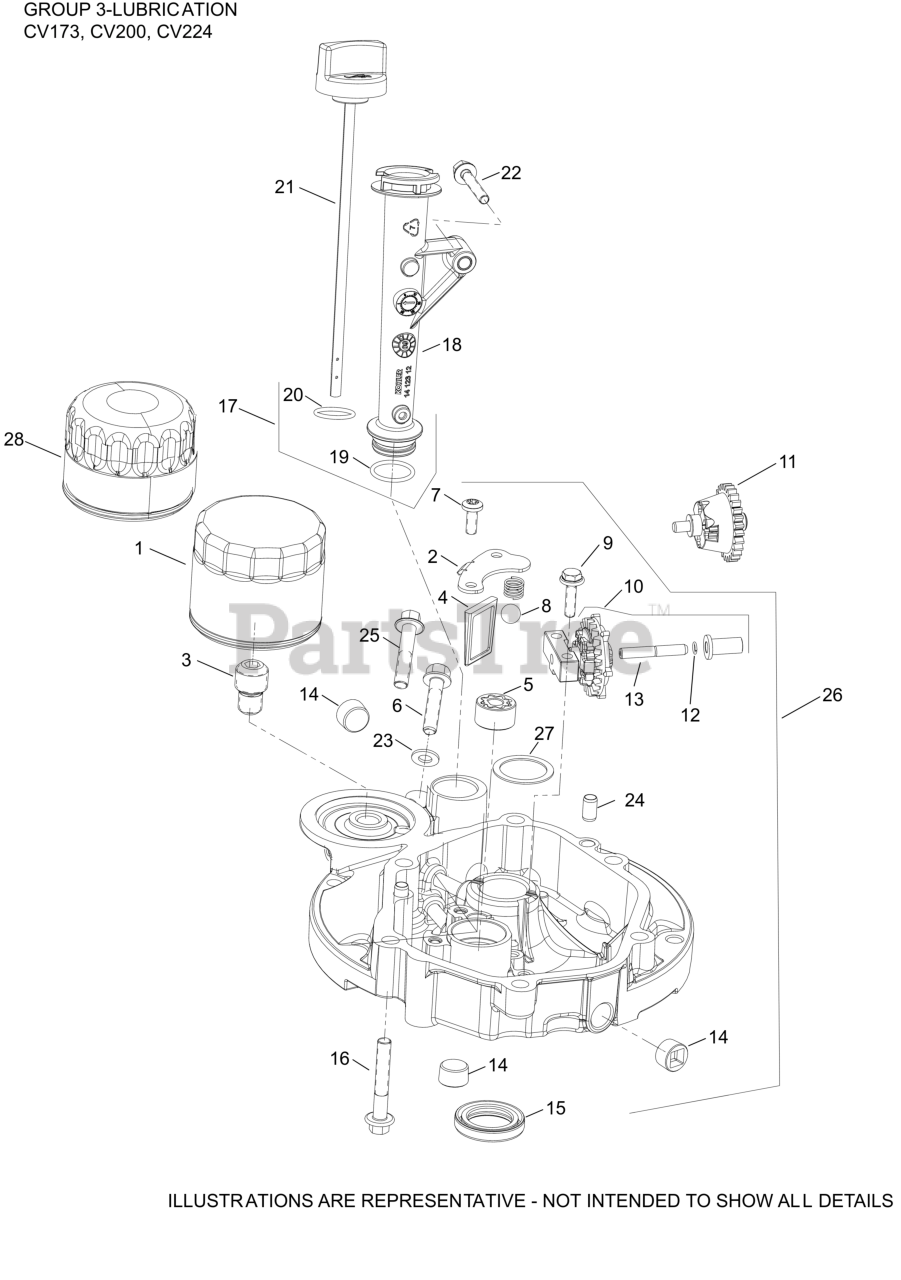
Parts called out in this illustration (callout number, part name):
1	FILTER, OIL
2	COVER, OIL PUMP SCREEN
3	NIPPLE, OIL FILTER
4	SCREEN, OIL
5	PUMP ASSEMBLY, OIL (GE-ROTOR)
7	SCREW, M6 X 16
8	BALL, STEEL COMPOSITE
9	SCREW, M6 X 22
10	GOVERNOR GEAR, ASSEMBLY
14	PLUG, PIPE (W/SEALANT)
16	SCREW, HEX FLANGE (M8)-USE 25 086 456-S
17	TUBE ASSEMBLY OIL FILL
19	O-RING, OIL FILL TUBE
20	O-RING (CAP)
22	SCREW, HEX FLANGE (M6)-(#25086435S)
23	WASHER, CLEAN OIL SCREW
24	PIN, DOWEL (8mm)
25	SCREW, CLOSURE PLATE
26	PAN, OIL ASSEMBLY (KIT)
